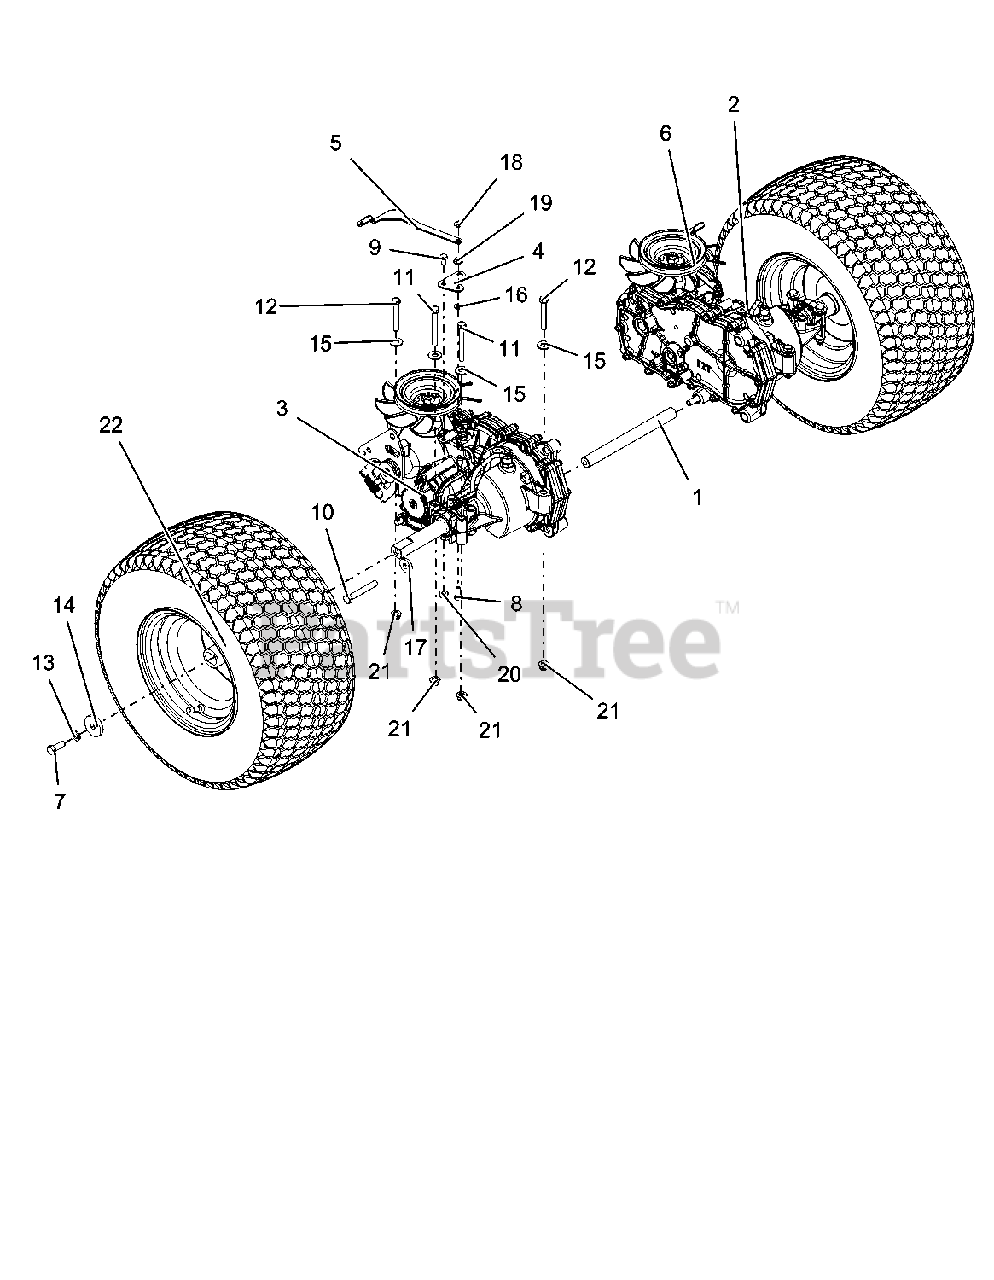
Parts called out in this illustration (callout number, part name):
1	ROD, TRANSAXLE BRACE
2	TRANSAXLE, LH EZT D-SHAFT SHORT
3	TRANSAXLE, RH EZT D-SHAFT SHORT
4	BRKT, DUMP VALVE EXTENSION
5	BRKT, VALVE DUMP RH
6	BRKT, VALVE DUMP LH
7	BLT-HEX .38-16X1.00 GR5 YWZC EP30
8	BLT-HEX .25-20X.75 GR5 YWZC
9	BLT-HEX .25-20X.50 GR5 YWZC
10	BLT-HEX .38-16X2.50 GR5 YWZC
11	BLT-HEX .31-18X2.75 GR5 YWZC
12	BLT-HEX .31-18X2.25 GR5 YWZC
13	WSHR-LK .38X.094 REG YWZC
14	WSHR-FL-STL .406X1.50X.245 YWZC
15	WSHR-FL-STL.38X.875X.083 YWZC
16	WASHER-FLAT-STL, .265 X .50 X .087
17	WSHR-FL-STL .406X1.00X.188 YWZC
18	NUT-LK-CTR-JAM .25-20 YWZC
19	@NUT-SPNLK-FLG .25-20 YWZC
20	NUT, LK-TOP-FLG .25-20 YWZC
21	NUT-LK-NYL-FLG .31-18 YWZC
22	ASSM TIRE\WHEEL, 18 X 8.50 - 8
